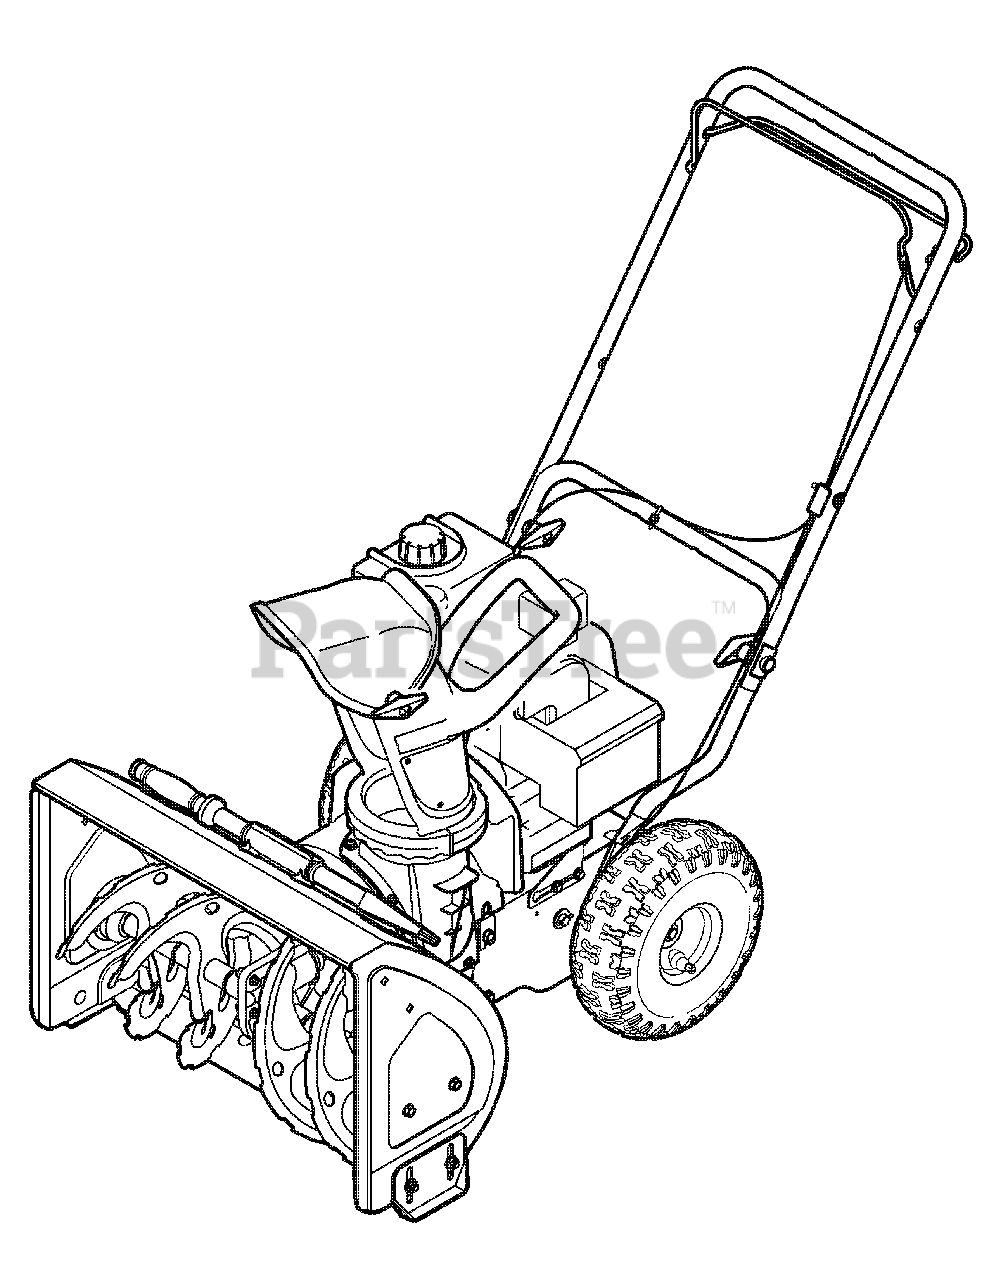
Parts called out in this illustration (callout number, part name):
NA	Extension Cord
NA	Lamp
NA	Spiral Crescent
NA	Rubber Paddle
NA	Friction Wheel Assembly
NA	Friction Wheel Rubber
